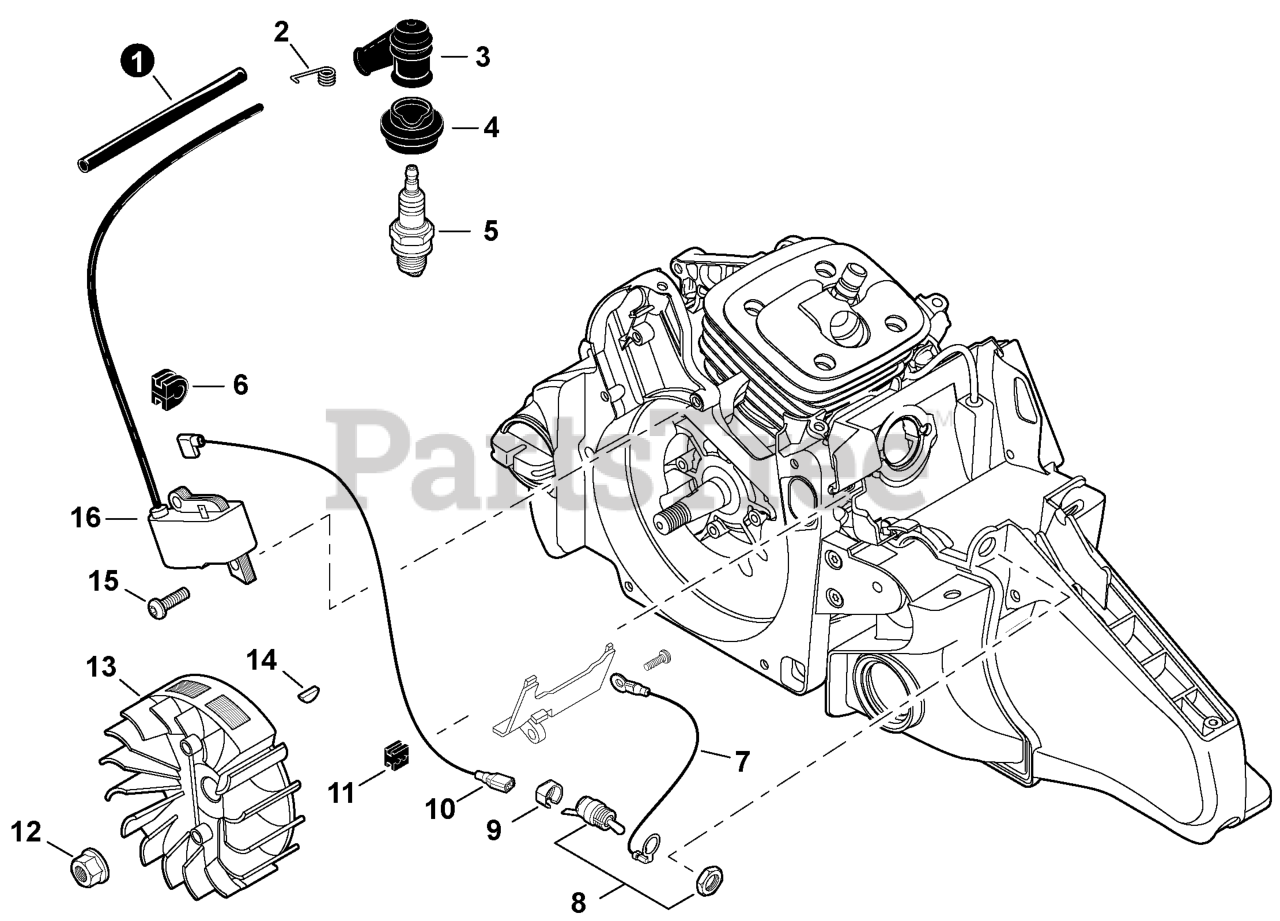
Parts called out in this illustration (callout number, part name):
1	TUBE, IGNITION COIL 6x7.2x70
2	TERMINAL, SPARK PLUG
3	CAP, SPARK PLUG
4	SEAL, SPARK PLUG
5	SPARK PLUG - BPM8Y
7	LEAD - GROUND L= 170
8	SWITCH, ON-OFF
9	CAP, SWITCH
10	LEAD - IGNITION L= 280
11	GROMMET, LEAD
12	NUT, FLANGE M8
13	FLYWHEEL
14	KEY, WOODRUFF
15	BOLT, TORX 5x16
16	COIL, IGNITION
